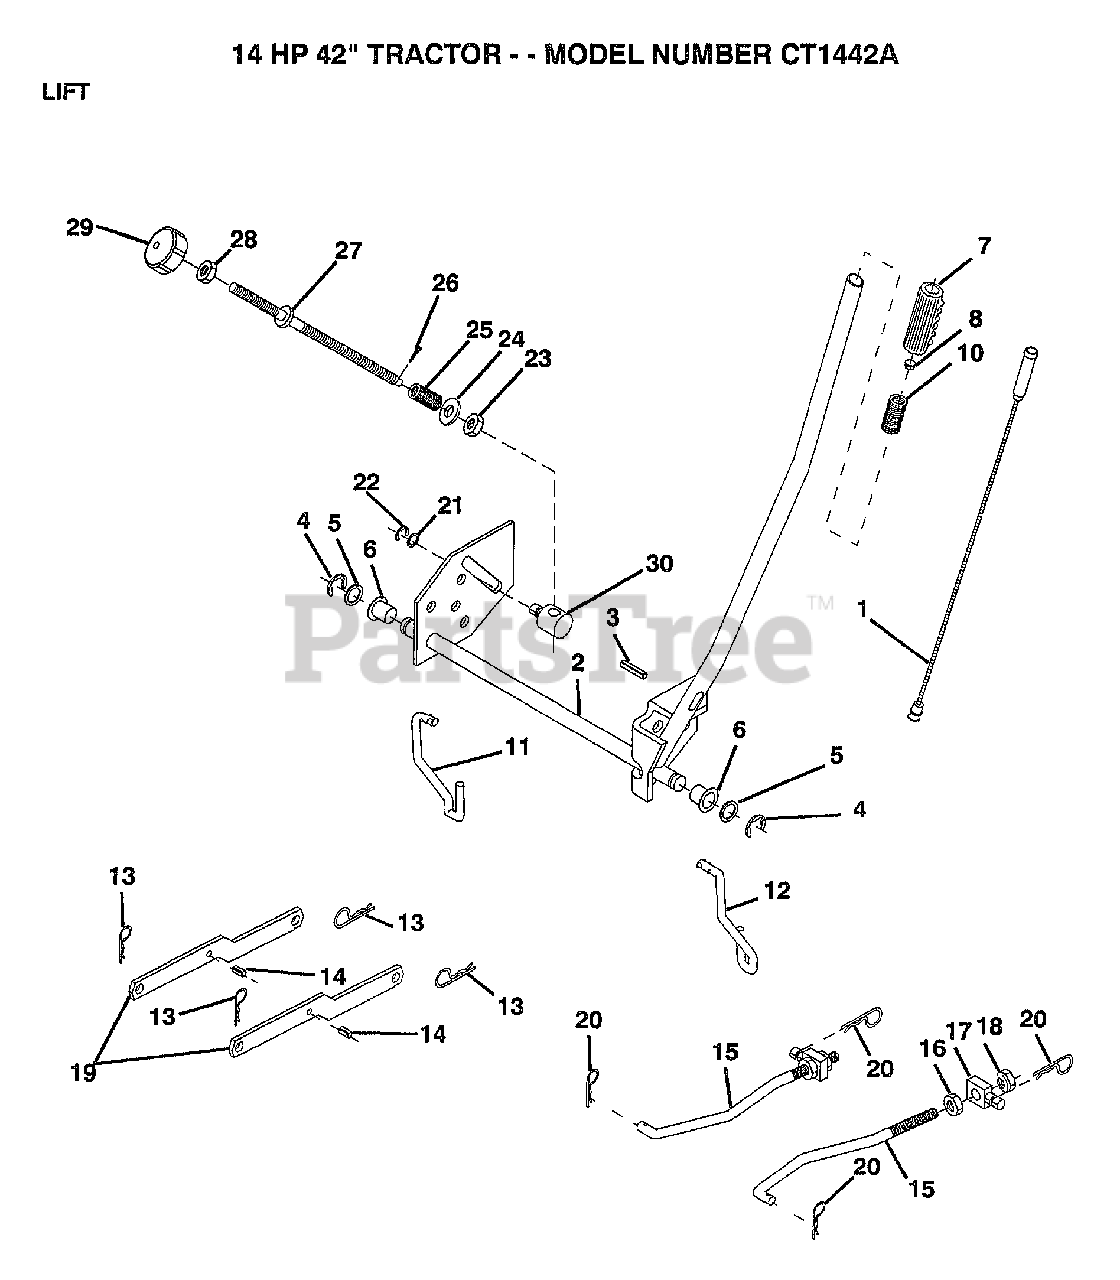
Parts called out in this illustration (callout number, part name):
1	WIRE ASM
3	PIN-GROOVE LT
5	WASHER
6	NYLON BEARING
7	GRIP
11	LINK LIFT LH
12	LIFT LINK RH
14	"PIN,SPRING"
15	LINK.FRONT
16	NUT
17	TRUNION
18	NUT.LK.W/WSH.1/2.
20	RETAINER.SPRING
21	WASHER
22	KLIP RING
23	NUT T
24	WASHER
25	SPRING T
28	NUT
30	TRUNION LT
